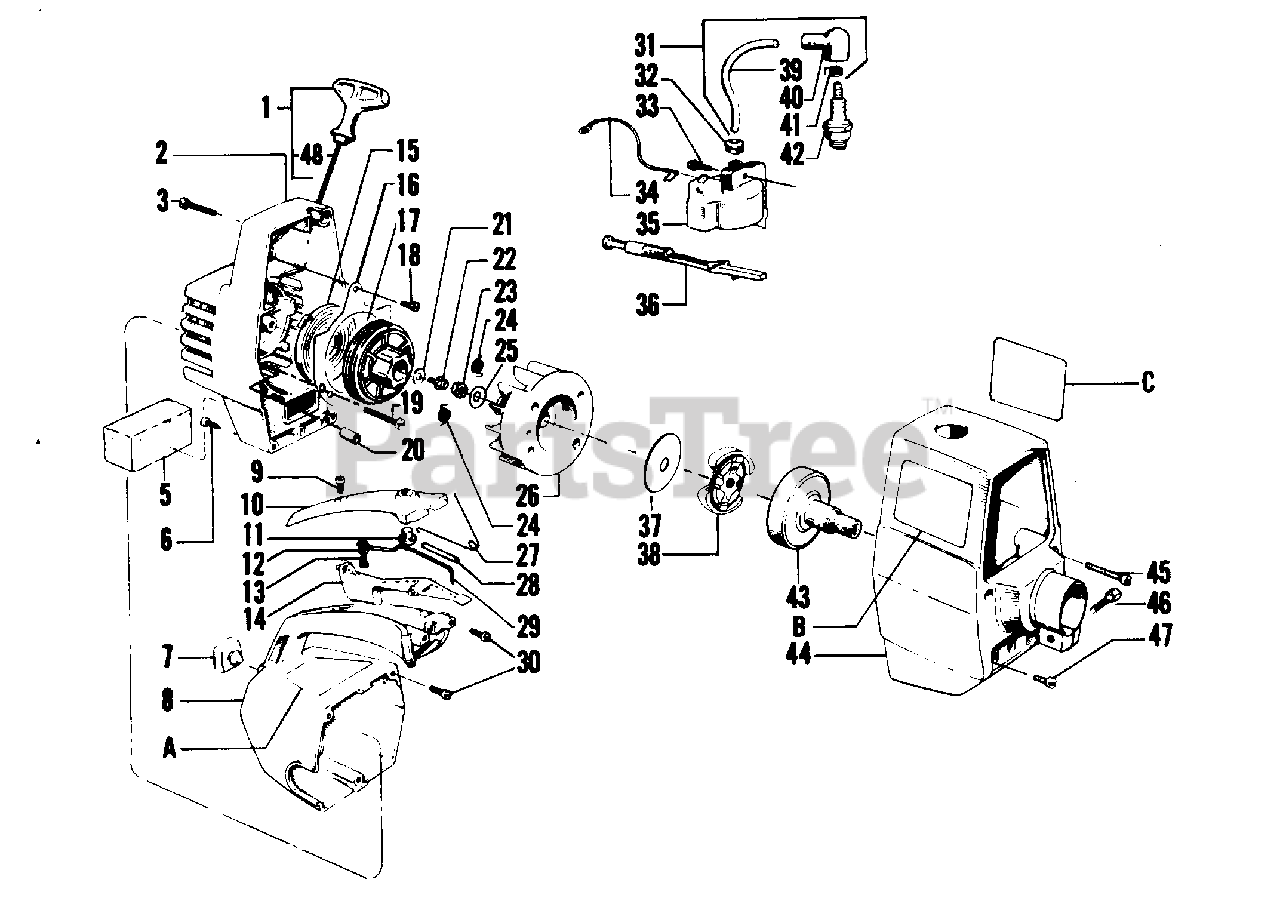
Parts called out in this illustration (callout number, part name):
2	Fan Housing Kit (Inc. 16, 18, 19, 20, 28) - See Service Ref. 6
3	Screw - 10 - 24 x 1-1/2 - Sems - Fan Hsg. - Top
5	Air Filter
6	Screw - 10 - 24 x 5/8 - Fan Hsg. - Bottom
7	Bumper -Fuel Tank Housing
8	Handle & Fuel Tank Housing
9	Screw - 8 - 16 x 3/4 - Pan Hd. - Handle Cover
10	Handle Cover
11	Button - Kill Switch
12	Washer - Kill Switch
13	Screw - 8 - 16 x 3/8 - Pan Hd. - Kill Switch
14	Trigger - Throttle
16	Air Baffle - See Service Ref. 6
18	Screw - #10 x 1/4 - Fil. Hd. - Air Baffle - See Service Ref. 6.
19	Screw - 10 - 24 x 1-3/16 Fil. Hd. - Air Baffle See Service Ref. 6.
21	Washer - Starter Pulley
22	Screw - #10 - 3/4 - Hex Washer Hd. - Starter Pulley
23	Nut - Flywheel - 5/16 x 24
24	Spring - Starter Dog
25	Washer - Flywheel
26	Flywheel Assembly (Inc. #24)
27	Trigger Spring
28	Insulation - Switch Spring
29	Spring - Kill Switch
30	Screw - 10 - 14 x 3/4 - Fan Hsg. to Handle and Fuel Tank
31	BEVEL GEAR COMPLETE
32	Grommet - Plug Wire
33	Screw - 8 - 32 x 3/4 - Fil. Hd. - Ignition Module
34	Lead Wire Switch
35	Kit - Ignition Module
36	Knob - Choke
37	Kit - Clutch - Washer - See Service Ref. 5
38	Kit - Clutch Ass'y. - See Service Ref. 1 & 5 (Inc. Clutch Washer)
39	High Tension Lead Wire
40	Boot - Spark Plug
41	Connector - Spark Plug Lead
42	Spark Plug
43	Coupling and Bearing Assembly
45	Screw - 10 - 24 x 1-1/3 Fil. Hd. - Shroud (Top)
46	Bolt - Pinch Clamp
47	Screw - 10 - 24 x 5/8 - Fil. Hd. - Shroud (Bottom)
48	Rope (3.5 ft.)
A	Decal - Starting Instructions
B	Decal - Shroud (Right) (Not a serviceable part)
C	Decal - Shroud (Left)
